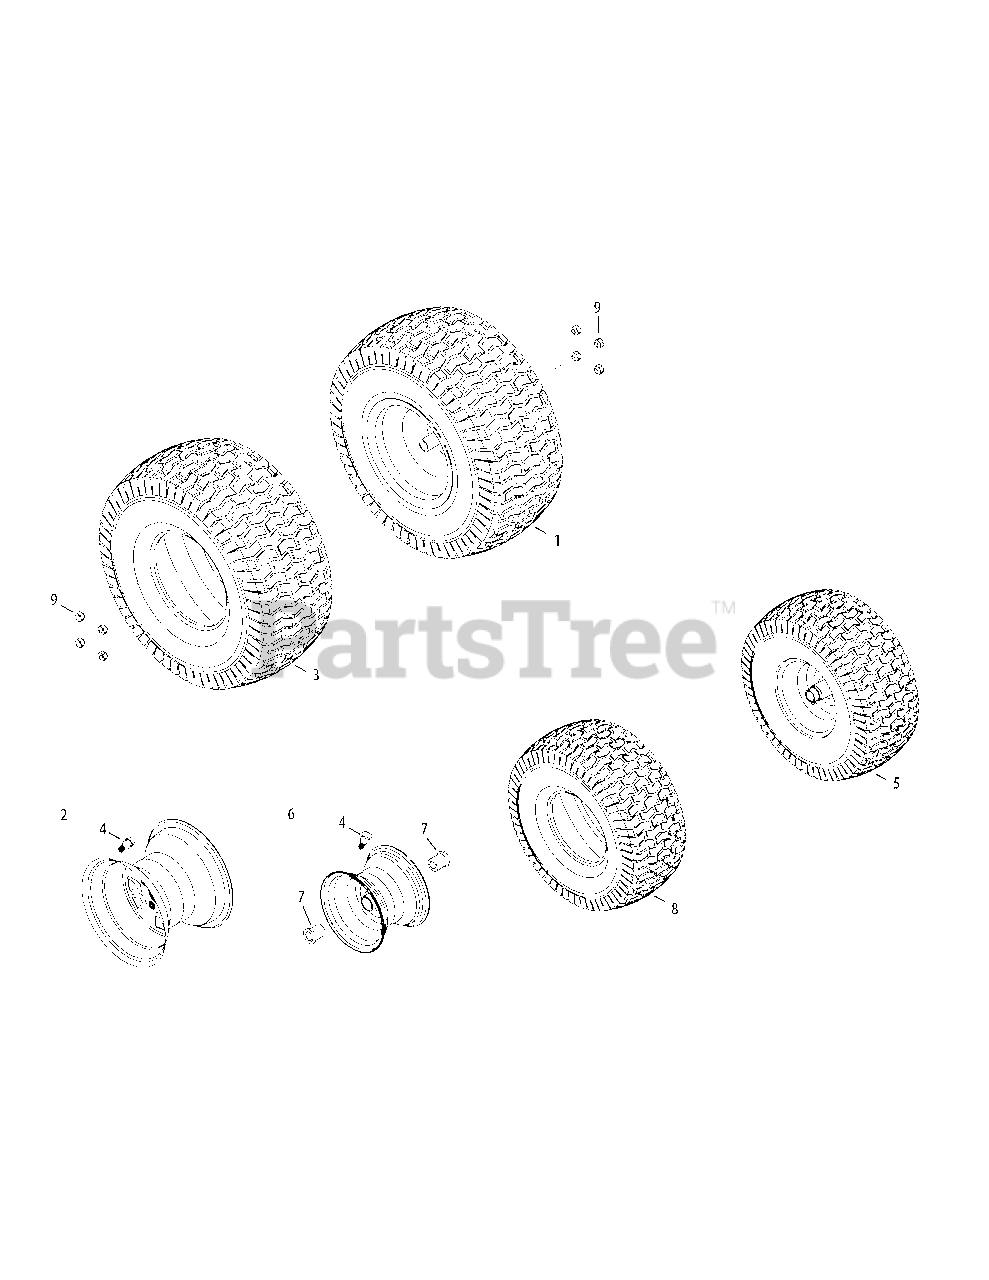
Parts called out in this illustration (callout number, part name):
1	Wheel, Complete, 22 x 9.5 x 12
2	Rim Ass’y, 12.0 x 7.0
3	Tire, 22 x 9.5 x 12 Sq Shoulder
4	Valve, Tubeless Air
5	Wheel, Complete, 16 x 6.5 x 8
6	Rim Ass’y, 8.0 x 5.38
7	Bearing, Flange, .760 ID
8	Tire, 16 x 6.5 x 8 Sq Shoulder
9	Lug Nut 7/16-14
